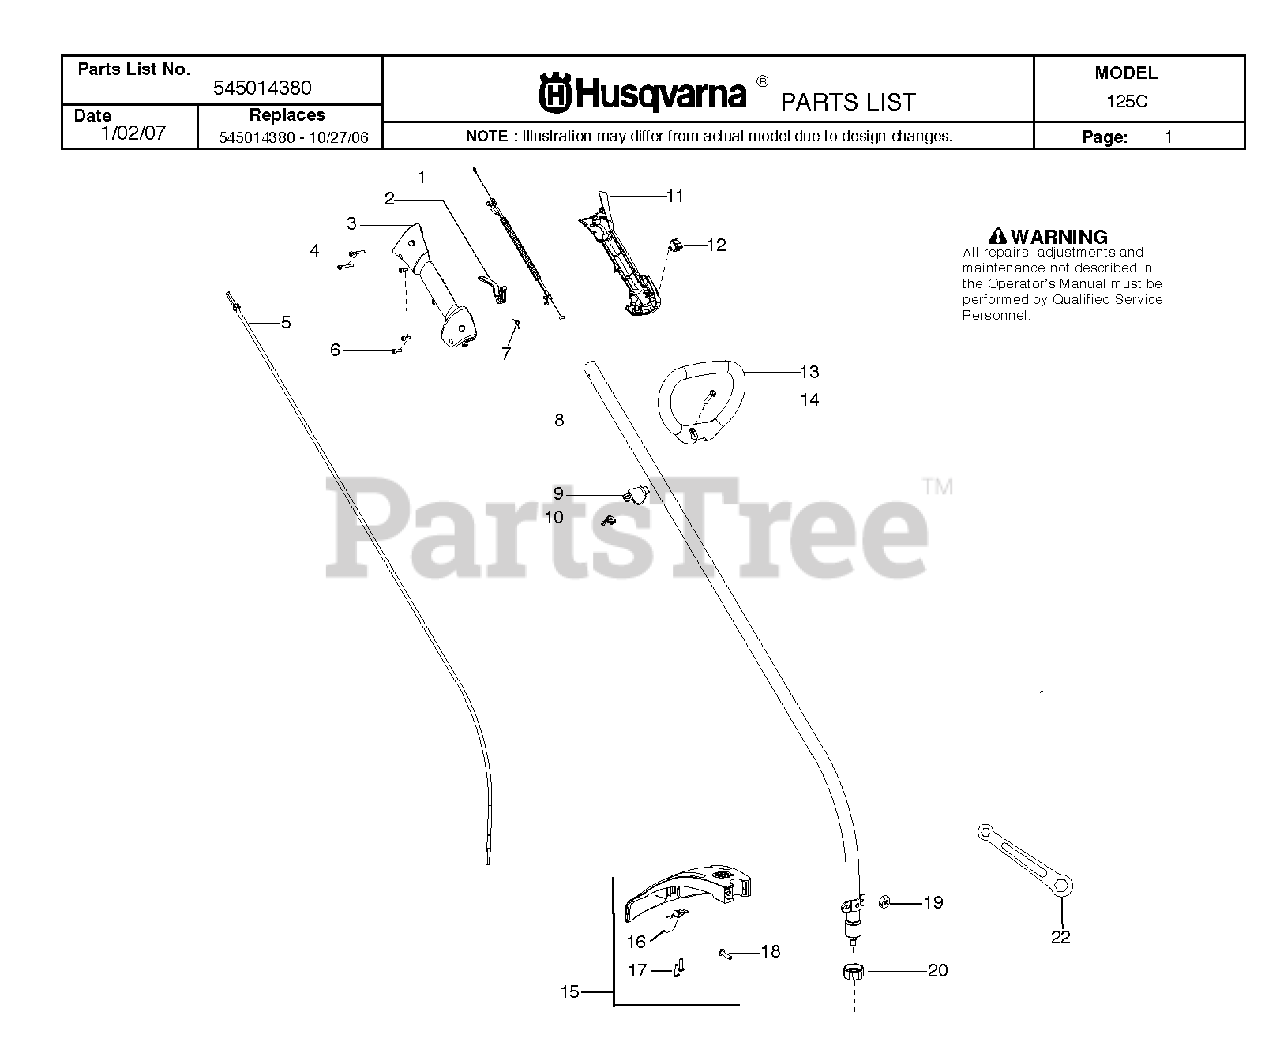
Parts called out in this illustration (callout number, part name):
1	Assy-Cable/Wire Harness
3	Housing-Throttle
5	Flexshaft
7	Spring-Trigger
8	Kit-Driveshaft
9	Clamp-Handle
10	Wingnut
11	Housing-Throttle
12	Kit-Switch
13	Handle-Assist
15	Kit-Shield
16	Limiter-Line
